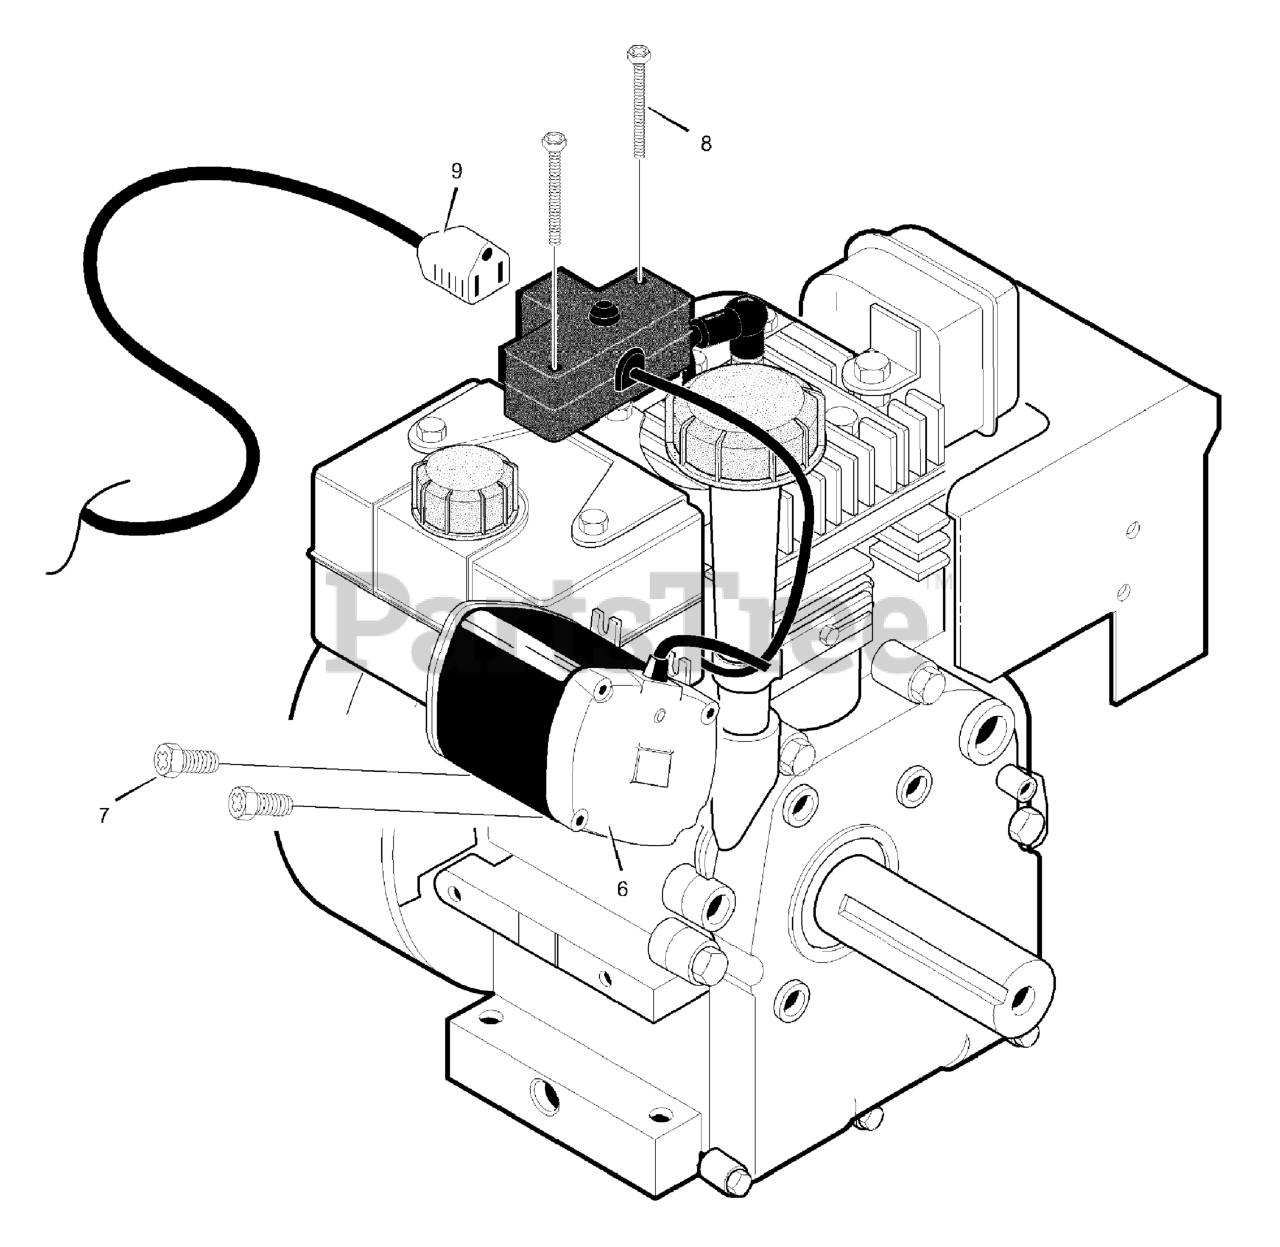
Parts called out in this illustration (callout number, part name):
6	MOTOR, STARTER
7	SCREW
8	SCREW
9	CORD, Electric, 10FT. 110V
